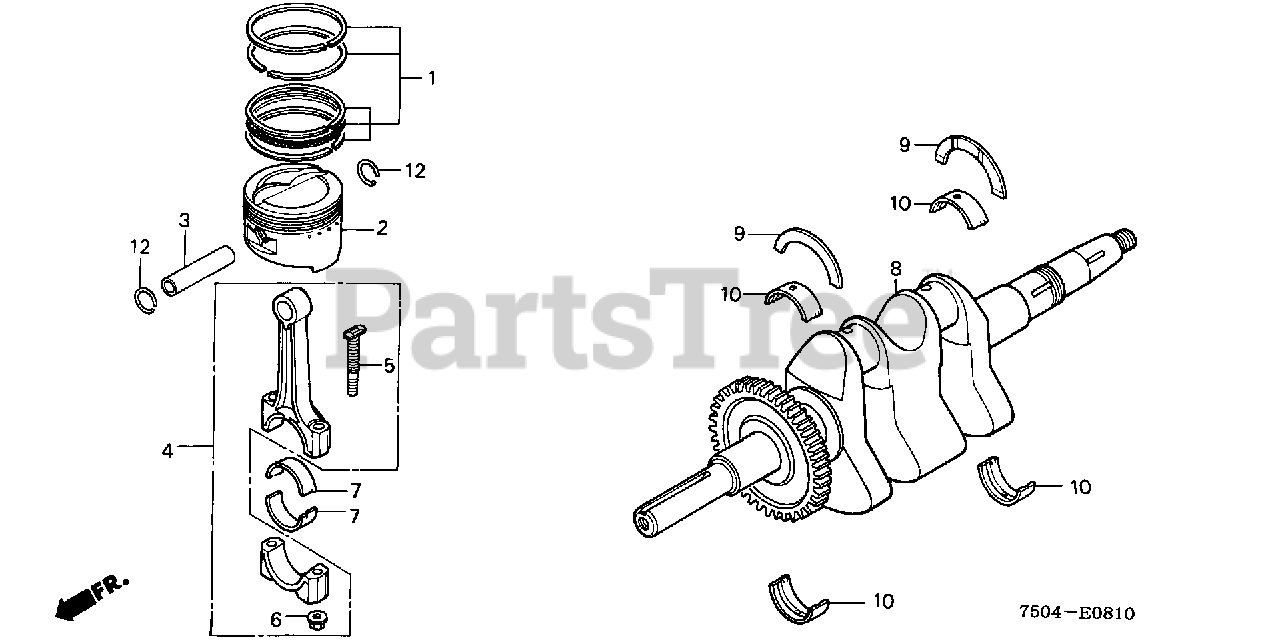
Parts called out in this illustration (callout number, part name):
1	RING SET, PISTON (STD)
1	RING SET, PISTON (OS 0.25)
1	RING SET, PISTON (OS 0.50)
2	PISTON (STD)
2	PISTON (OS 0.25)
2	PISTON (OS 0.50)
3	PIN, PISTON
4	ROD ASSY., CONNECTING
5	BOLT, CONNECTING ROD
6	NUT, CONNECTING ROD
7	BEARING A, CONNECTING ROD (BLACK)
7	BEARING B, CONNECTING ROD (BROWN)
7	BEARING C, CONNECTING ROD (GREEN)
7	BEARING D, CONNECTING ROD (YELLOW)
7	BEARING E, CONNECTING ROD (RED)
8	CRANKSHAFT
9	BEARING, CRANKSHAFT THRUST
10	BEARING, CRANKSHAFT (1) (BLACK)
10	BEARING, CRANKSHAFT (2) (BROWN)
10	BEARING, CRANKSHAFT (3) (GREEN)
10	BEARING, CRANKSHAFT (4) (YELLOW)
10	BEARING, CRANKSHAFT (5) (RED)
12	CLIP, PISTON PIN (14MM)
